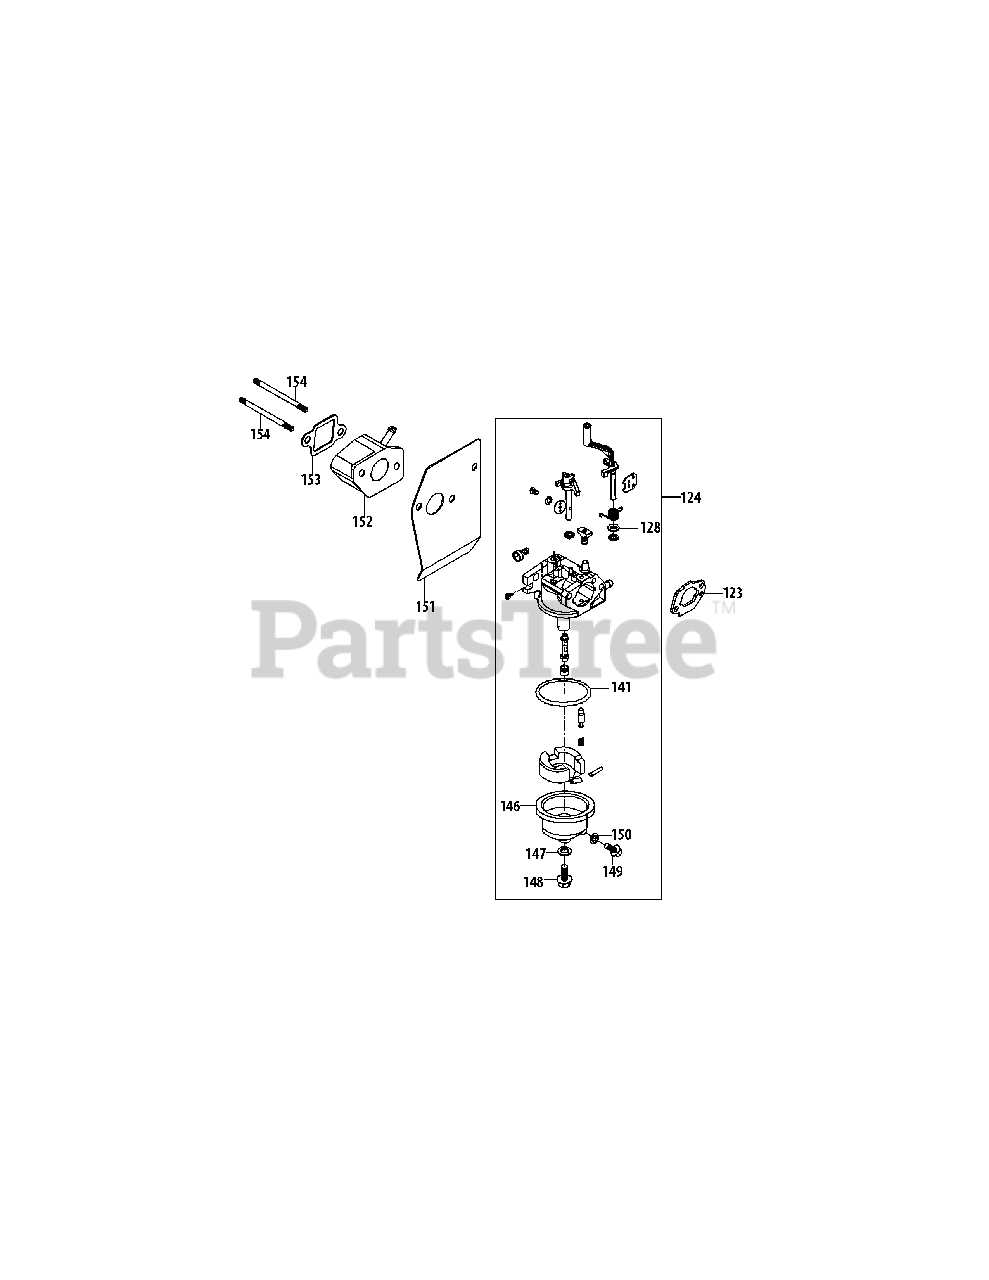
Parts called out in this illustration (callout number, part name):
123	Carburetor Gasket Plate
124	Carburetor Assembly
128	Choke Shaft Washer
141	Fuel Bowl O-Ring
147	Fuel Bowl Gasket
148	Fuel Bowl Mounting Bolt
149	Fuel Drain Plug
150	Fuel Drain Plug Gasket
151	Carburetor Gasket
152	Carburetor Insulator
153	Carburetor Insulator Gasket
154	Stud M6×113
